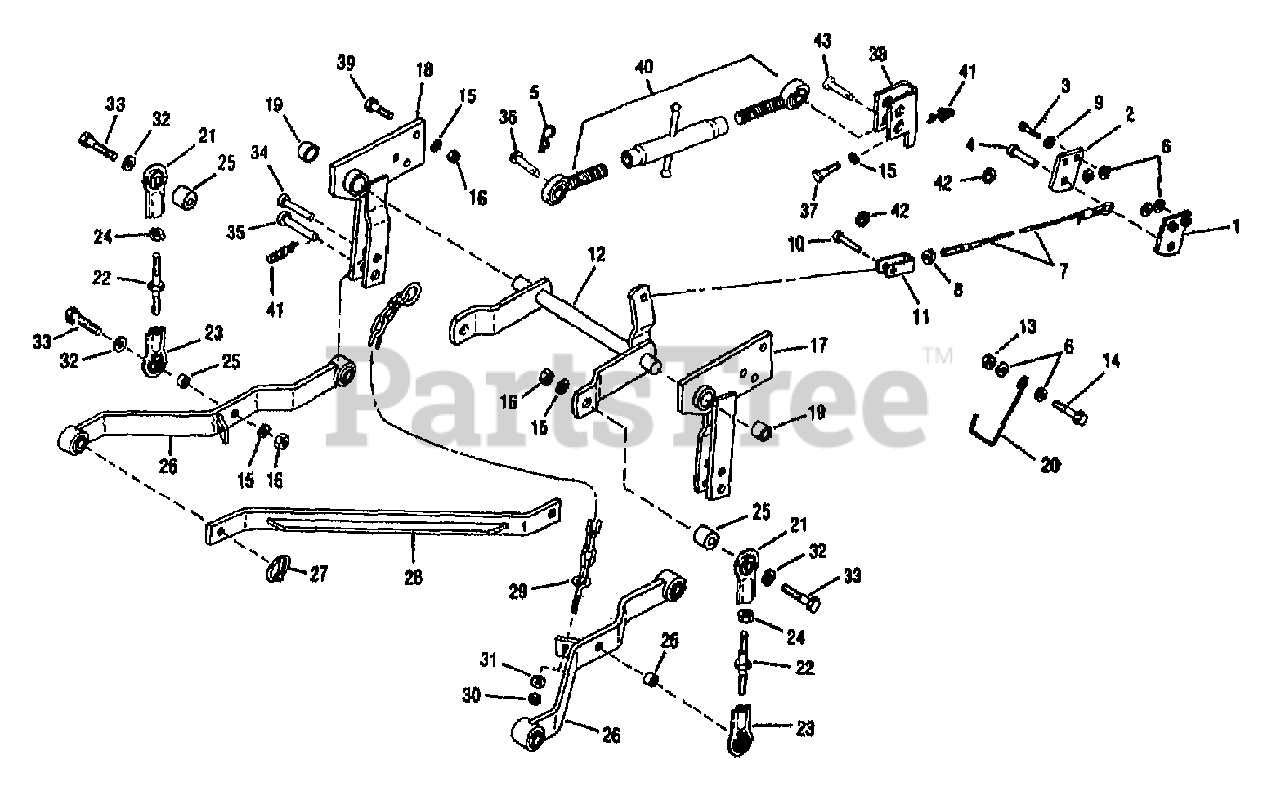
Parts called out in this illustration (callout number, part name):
1	ASSM-LIFT ARM
3	SCR-HH 3/8-16X1.5 G5 ZP
4	PIN-CLEVIS .5X1.437 ZP
5	BRAKE-ARM
6	WASHER-.875X.390X.134
7	CABLE-LIFT
8	NUT-HEX/JAM 3/8-16
9	WASHER-LK .375 @ DEPL
10	PIN-CLEVIS .5X1.25
11	YOKE-CABLE
12	ASSM-PIVOT SHAFT
13	NUT-H/LK 3/8-16
14	SCR-HFLK 3/8-16X1.25 ZP
15	WASHER-LK .5
16	NUT-HEX JAM 1/2-13
17	ASSM-HITCH RH
18	ASSM-HITCH LH
20	GUIDE-CABLE
22	ASSM-STUD
24	NUT-JAM
25	SPACER-.656X.512X.297
27	PIN-RETAIN
30	NUT-TOP/LK 5/16-18 ZP
31	WASHER-.88X.343X.1345
32	WASHER-.685X.515X.059
33	SCR-HH 1/2-13X2.25 G5 ZP
34	PIN-CLEVIS .62X2.50 ZP
35	PIN-CLEVIS .75X2.5
36	PIN-CLEVIS .62X2.50 ZP
37	SCR-HH 1/2-13X1.0 G5 ZP
39	SCR-HH 1/2-13X1.25 G5 ZP
40	ASSM-UPPER LINK
41	RING-COTTER
42	RING-CIRCLE COTTER
43	PIN-CLEVIS
